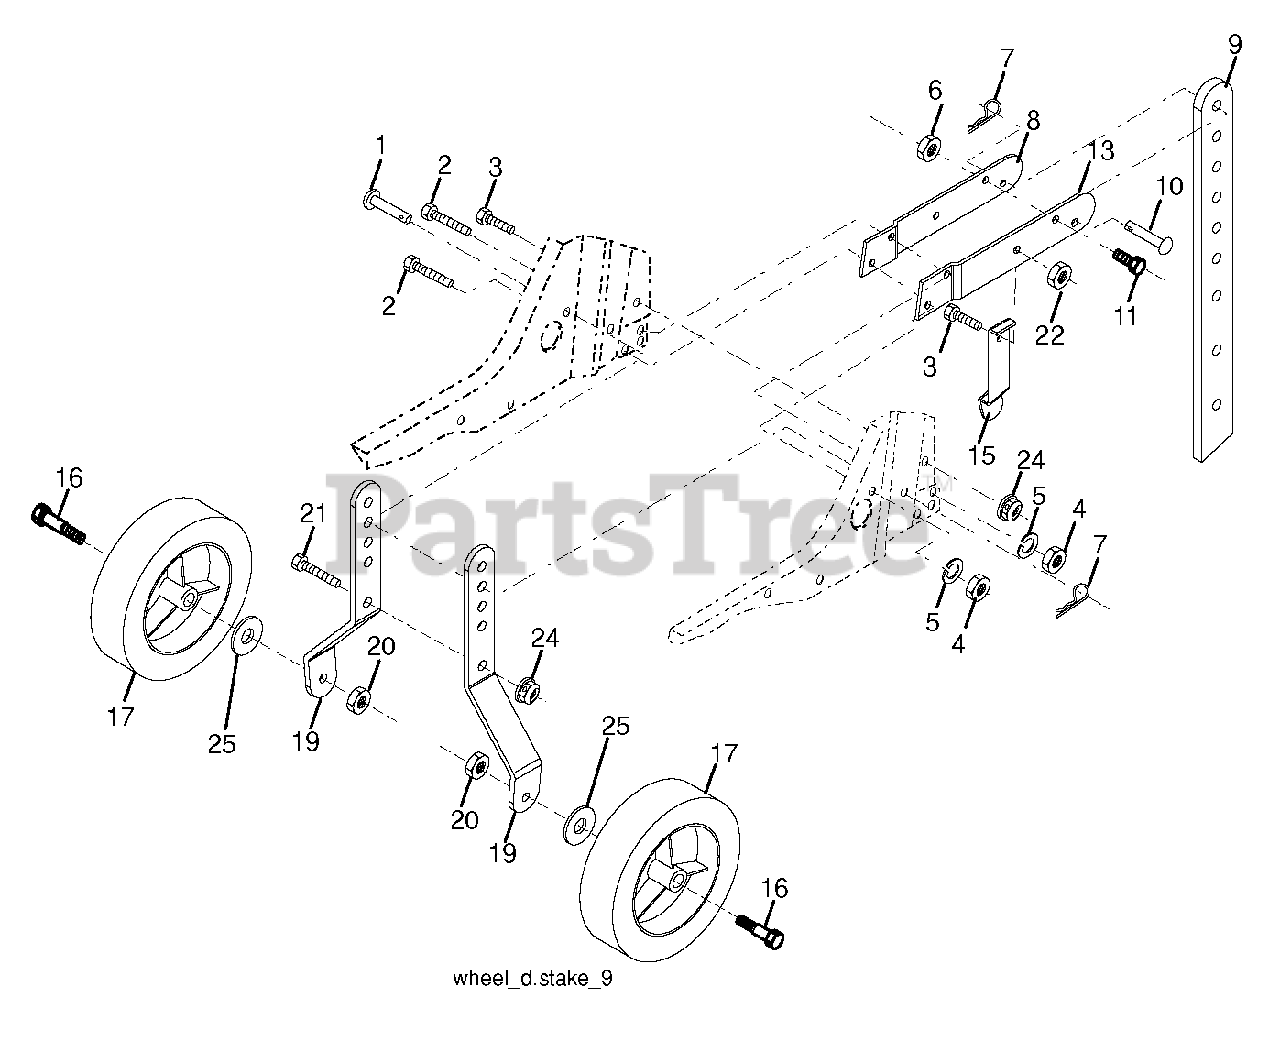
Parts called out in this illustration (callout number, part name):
1	PIN.CLEVIS.HD.25X1.75.TILLER
2	BOLT
3	BOLT
5	LOCKWASHER
6	NUT
8	SUPPORT.STAKE.DEPTH.RH.BLACK
9	STAKE.DEPTH.13.25.W/9HOLES
10	RIVET.PAN.HD.DRILLED
11	Bolt
13	SUPPORT.STAKE.DEPTH.LH.BLACK
15	SPRING.STAKE
16	BOLT.SHOULDER
17	WHEEL 8X1.75.5SPK MAG.BRK 421
19	BRACKET.WHEEL.BLACK
20	LOCKNUT
22	NUT.71038.31-18.HEX.NYLOCK
24	LOCKNUT-FLANGE 5/16-18
